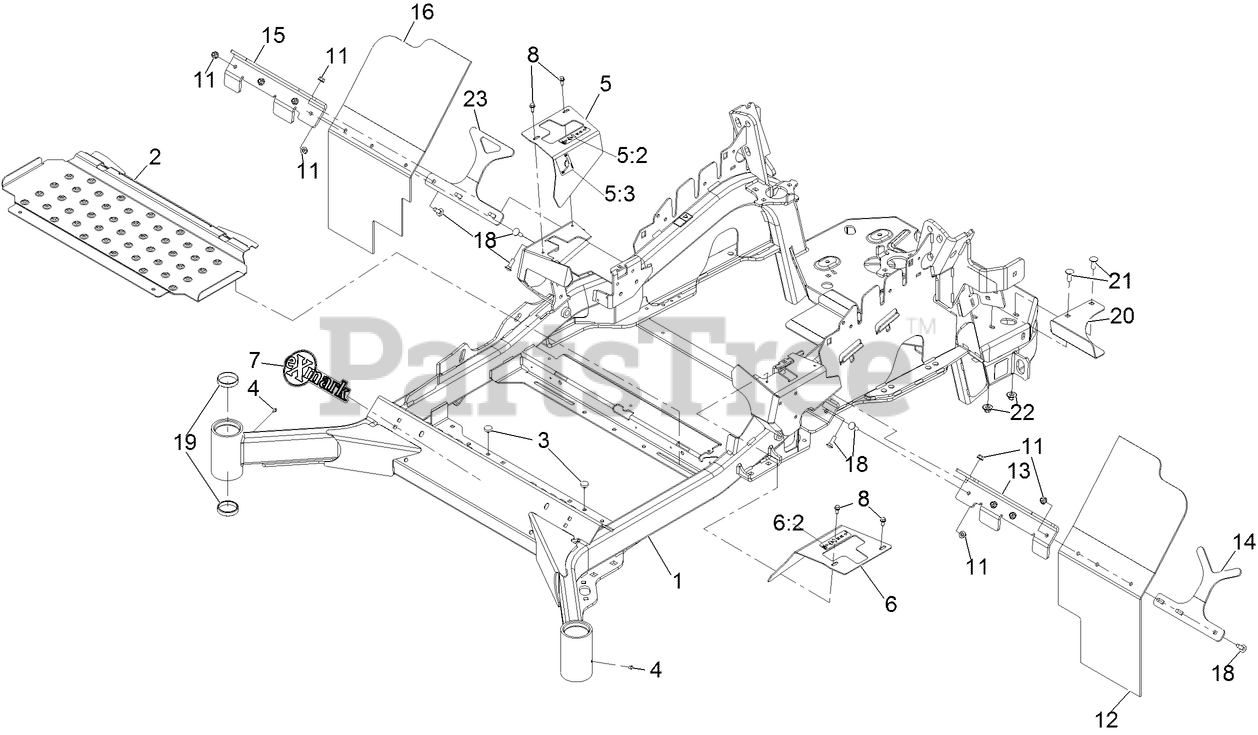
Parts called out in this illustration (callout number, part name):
1	Mainframe ASM
2	FLOOR PAN
5	RH MOTION CONTROL COVER ASM
5:2	DECAL-CONTROL, MOTION
5:3	DECAL-PARK BRAKE, CE
6	LH MOTION CONTROL COVER ASM
6:2	DECAL-CONTROL, MOTION
7	DECAL-EXMARK
8	SCREW-HWH
11	NUT-HF, NI
12	Mud Flap
13	Bracket-Mud Flap, LH
14	Support-Mud Flap, Rear
15	Bracket-Mud Flap, RH
16	Mud Flap
18	BOLT-CARR
19	CUP-BEARING
20	SHIELD-HEAT
21	SCREW-CARR
22	Nut-Nyloc 3/8-16 Flg
23	SUPPORT-MUD FLAP RH
